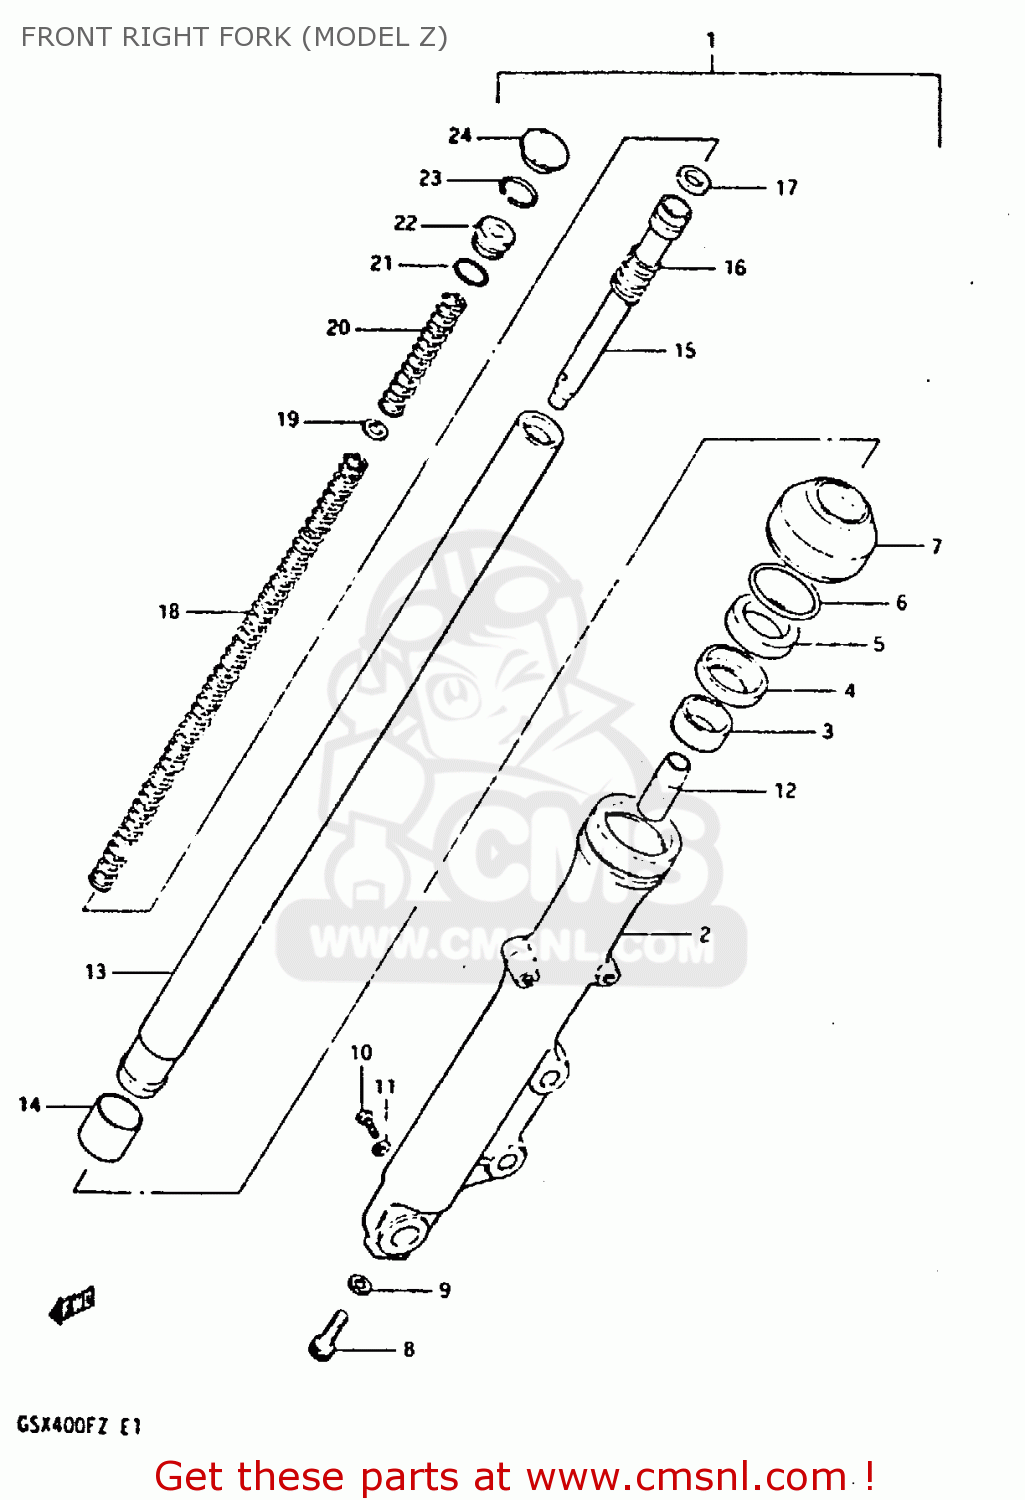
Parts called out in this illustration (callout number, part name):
1	DAMPER ASSY, RH
2	OUTER TUBE RH
3	BUSH,GUIDE
4	SPACER,OIL SEAL
5	OIL SEAL,FRONT FORK
6	CIRCLIP,FORK OIL SEAL
7	DUST SEAL
8	BOLT(8X27)
9	GASKET (NAS)
10	BOLT
11	GASKET,DRAIN,PLUG (NAS)
12	PIECE,OIL LOCK
13	INNER TUBE
14	BUSH
15	CYLINDER
16	SPRING,REBOUND
17	RING,PISTON
18	SPRING (B)
19	SEAT,SPRING
20	SPRING A
21	O RING
22	SEAT,SPRING
23	RING,STOPPER
24	CAP
